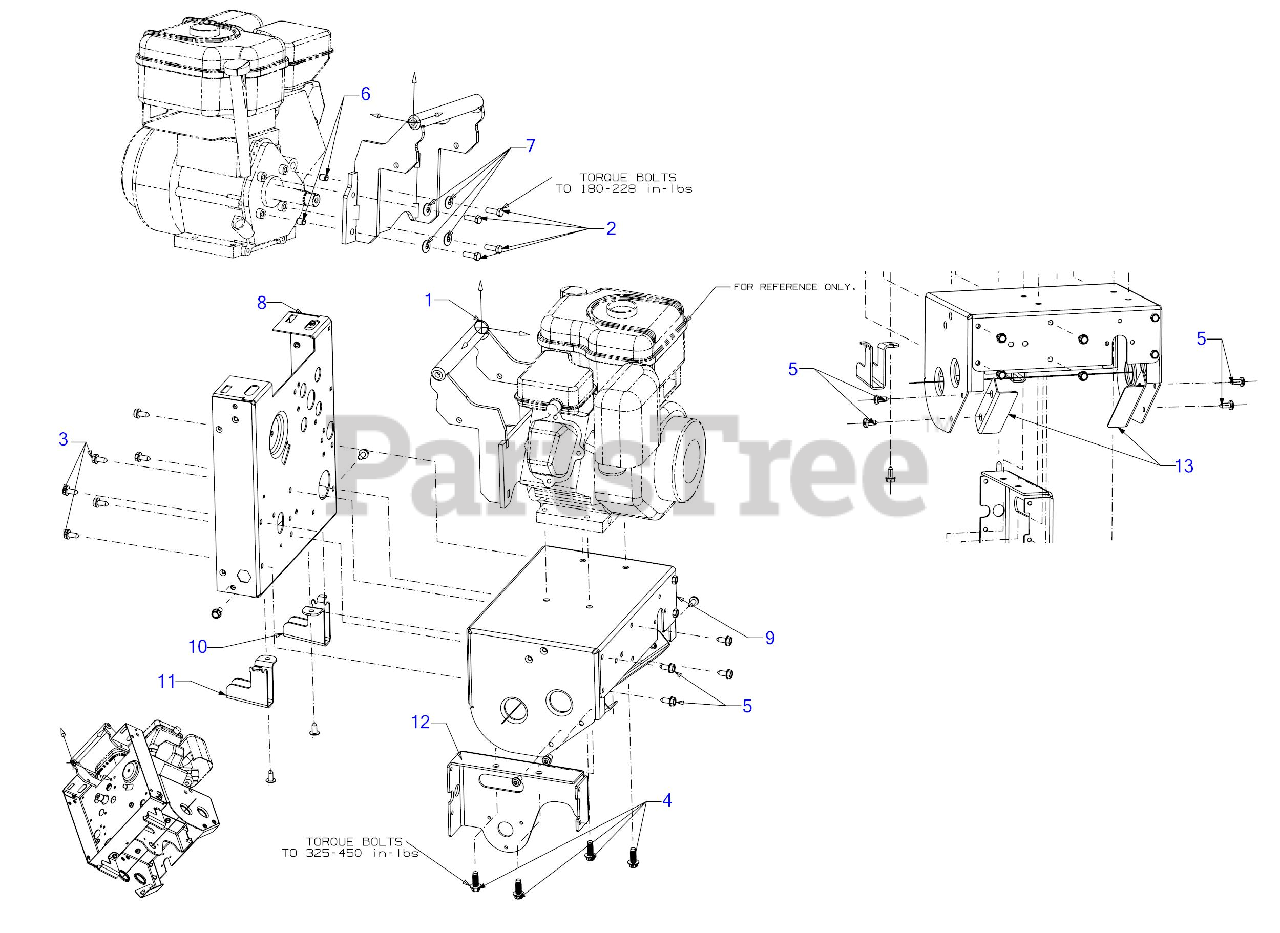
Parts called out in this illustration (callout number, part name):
1	UPPER CATCHER
2	HEX HEAD CAP SCREW 5/16-24 x 1.00 GR5
3	SCREW 5/16-18 x .750
4	SCREW 3/8-16 x 1
5	SCREW 5/16-18 x .750
7	BELL WASHER .337 X.867 x .057
8	DRIVE HOUSING
10	BRACKET-TIP (RH)
11	BRACKET-TIP (LH)
12	SUPPORT BRACKET SHAFT
13	LOWER FRAME COVER
